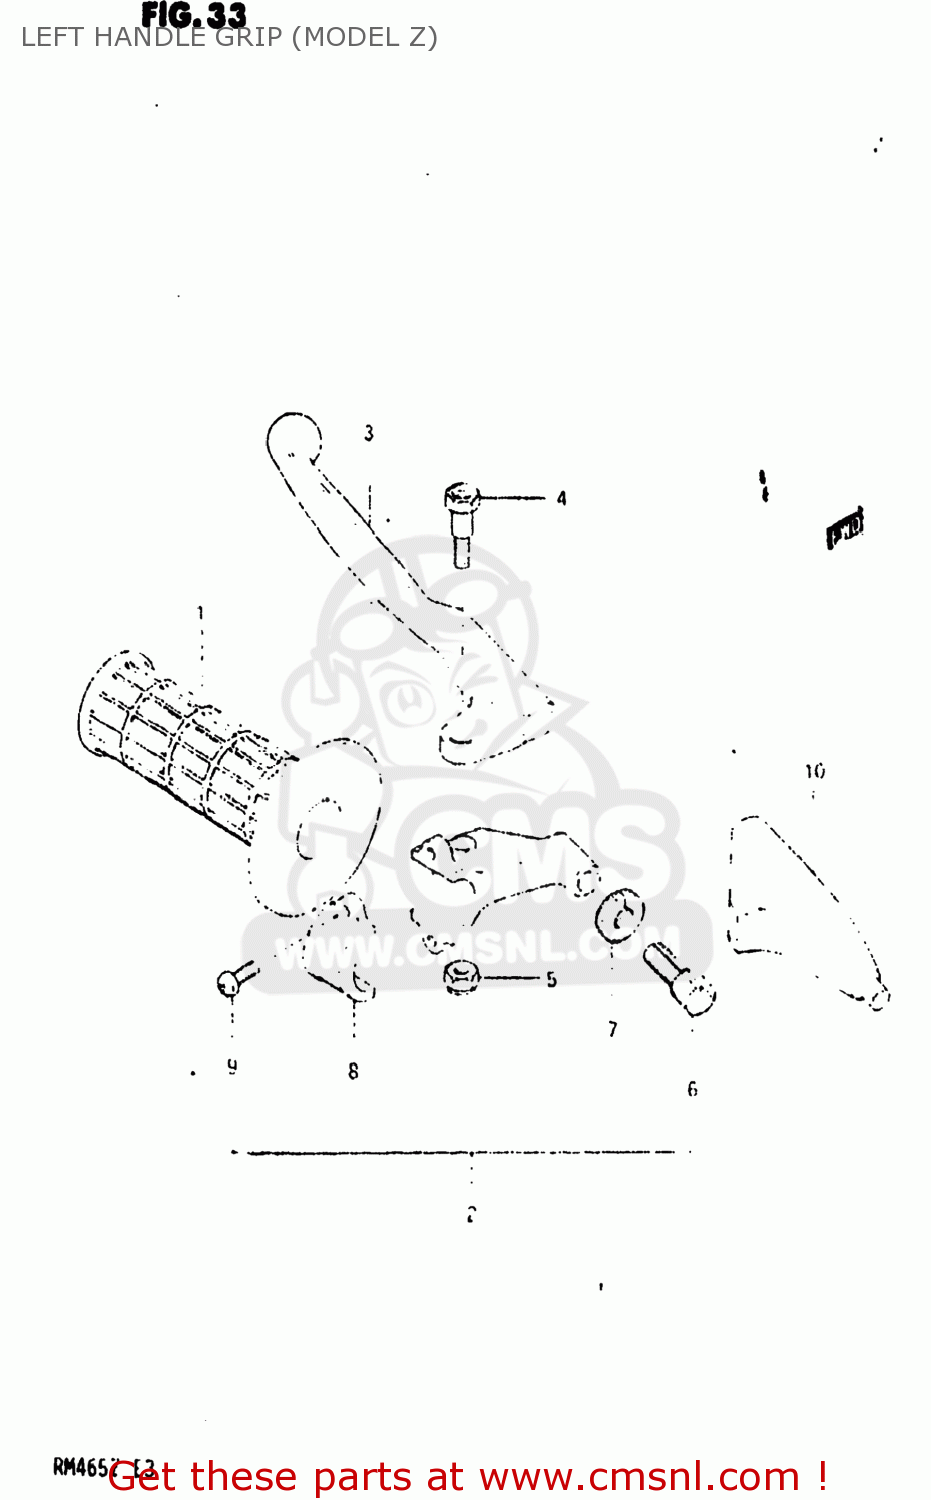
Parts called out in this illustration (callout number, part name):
1	GRIP,LEFT
2	LEVER ASSY,CLUTCH
3	LEVER,CLUTCH
4	BOLT,LEVER
5	NUT 6MM
6	ADJUSTER,CABLE
7	NUT,CABLE ADJUSTER
8	BRACKET,CLUTCH LEVER HOLDER
9	SCREW
10	COVER,CLUTCH LEVER
